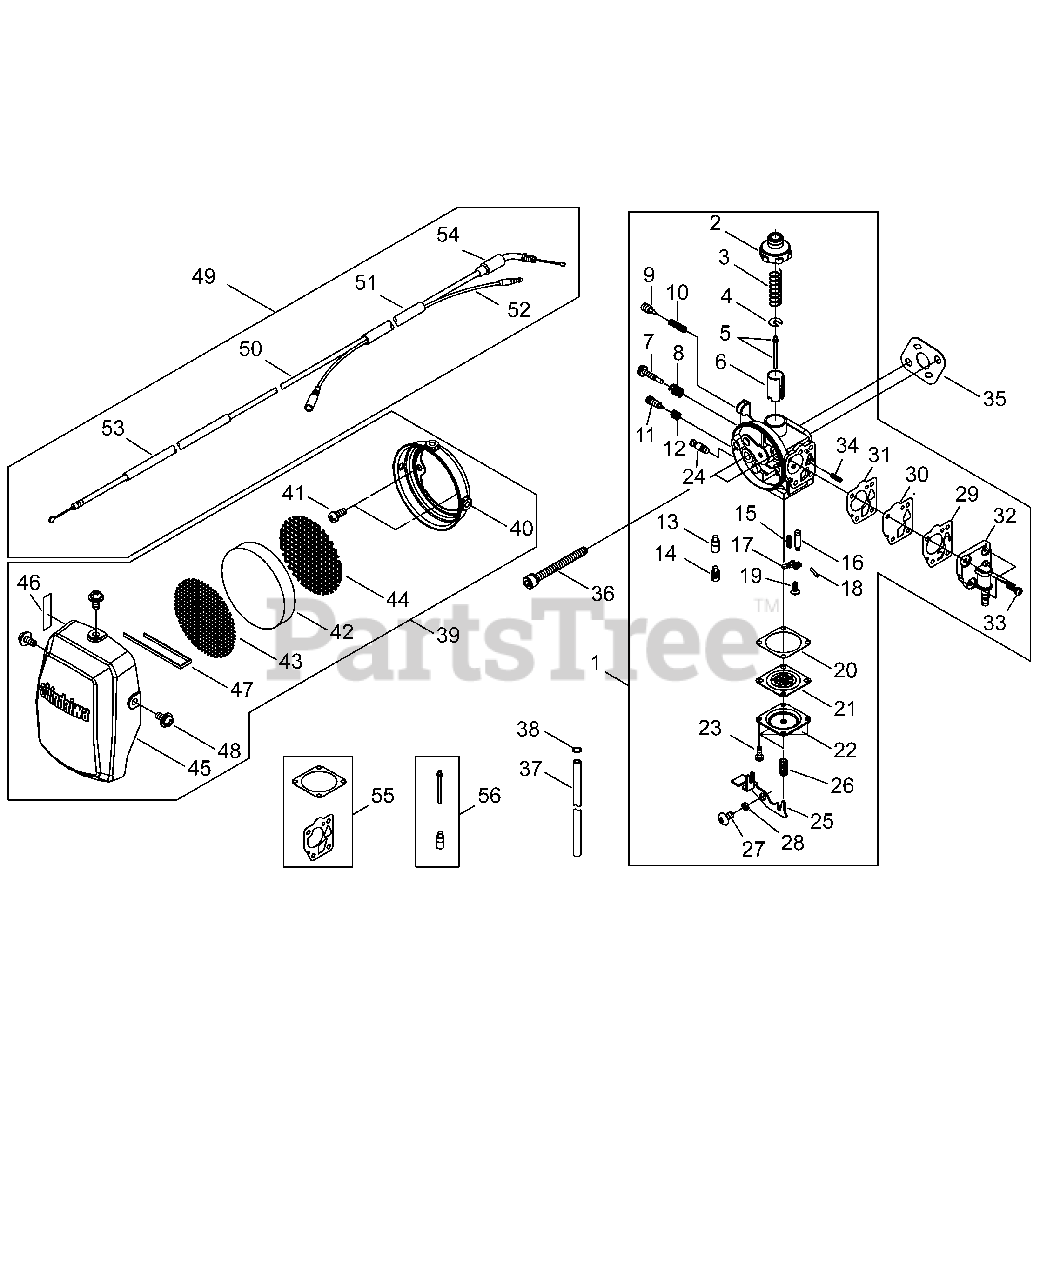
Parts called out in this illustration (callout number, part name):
1	CARBURETOR
2	CAP, THROTTLE
3	SPRING
4	WASHER, SPRING SUPPORT
5	NEEDLE, JET
6	VALVE, THROTTLE
7	SCREW, IDLE ADJUST
8	SPRING
9	SCREW, SLOW AIR
10	SPRING
11	SCREW, MAIN ADJUST
12	SPRING
13	JET, MAIN
14	HOLDER, MAIN JET
15	SPRING
16	VALVE, INLET NEEDLE
17	LEVER, METERING
18	PIN, METERING LEVER
19	SCREW M3×8
20	GASKET, METERING DIAPHRAGM
21	DIAPHRAGM, METERING
22	COVER, DIAPHRAGM
23	SCREW M3×8
24	VALVED, OVERFLOW
25	LEVER, TICKLER
26	SPRING
27	SCREW
28	COLLAR
29	VALVE, PUMP
30	DIAPHRAGM, METERING
31	GASKET, DIAPHRAGM
32	BODY, PUMP
33	SCREW
34	SPRING, COIL
35	GASKET, CARBURETOR
36	BOLT M5×50
37	PIPE, FUEL
38	CLIP Ø6
39	FILTER ASSY, AIR
40	CASE, AIR FILTER
41	SCREW
42	FILTER, AIR
43	SCREEN - OUTER
44	SCREEN, REAR
45	COVER, AIR FILTER
46	LABEL, CHOKE
47	CLIP, FILTER RETAINING
48	SCREW 4
49	THROTTLE CONTROL ASSY
50	CABLE, THROTTLE
51	SLEEVE
52	LEAD - GROUND
53	TUBE, THROTTLE CABLE
54	CAP, THROTTLE CABLE
55	GASKET KIT
56	NEEDLE KIT, JET
